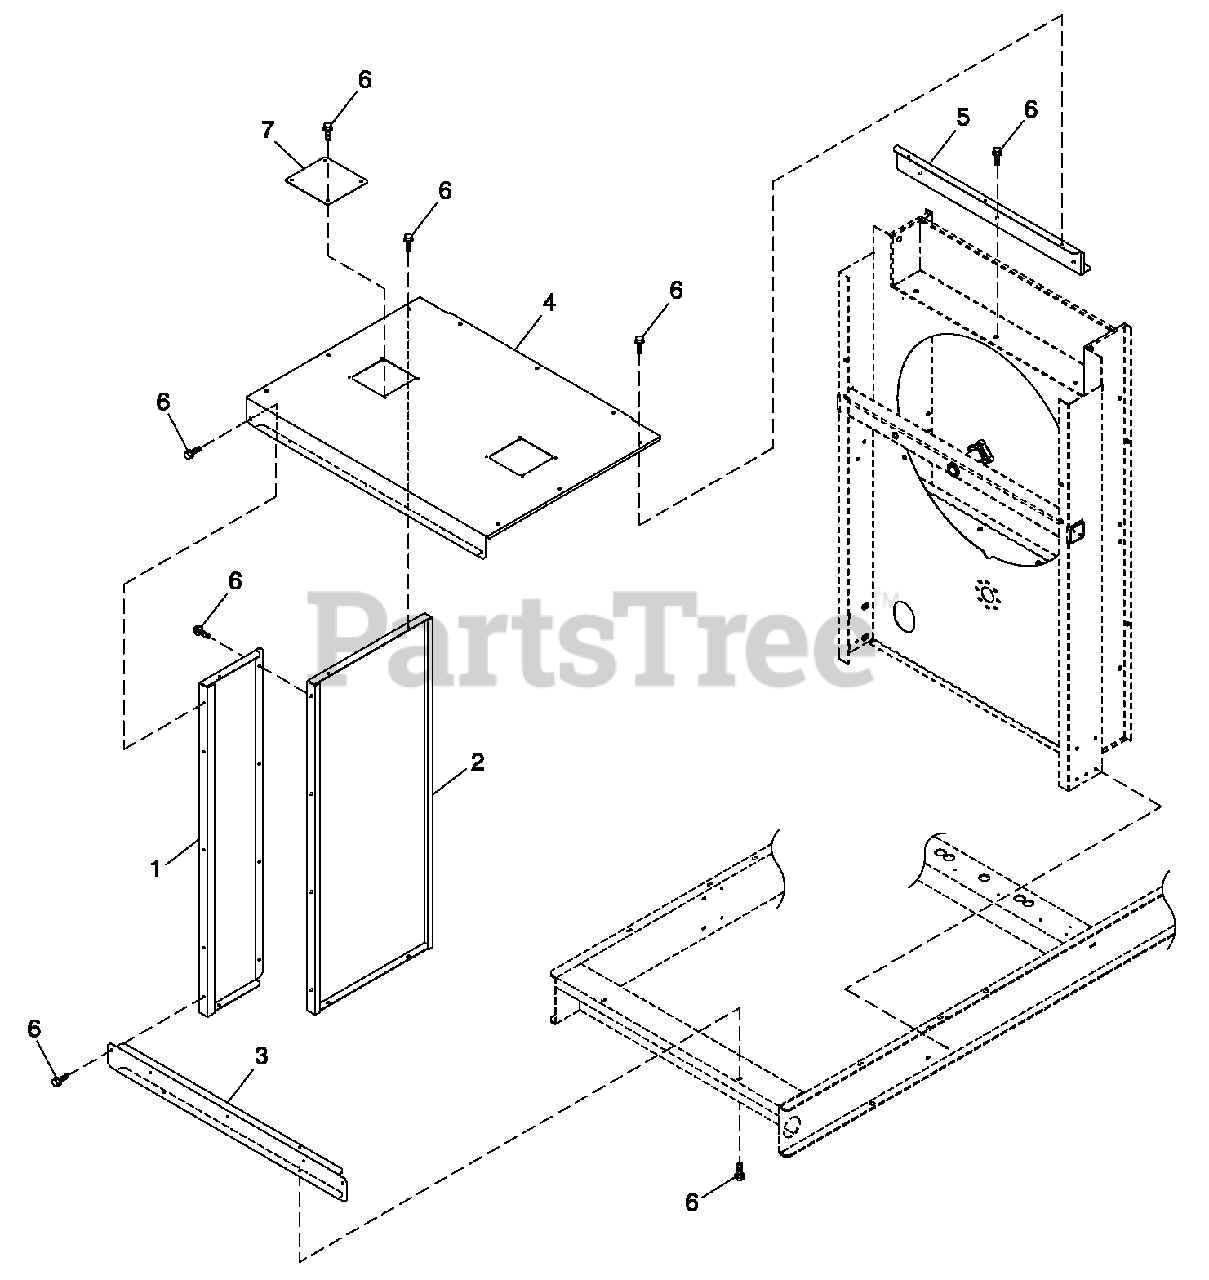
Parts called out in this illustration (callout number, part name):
1	PANEL C5 FRONT SIDES
2	PANEL C5 REAR SIDES
3	PANEL LOWER FRONT
4	PANEL C5 TOP
5	PANEL C5 TOP MOUNT
6	SCREW THF M6-1 X 16 N WA Z/JS
7	ACCESS COVER 160 X 170 GALV
8	SCREW THF M6-1 X 16 N WA Z/JS
